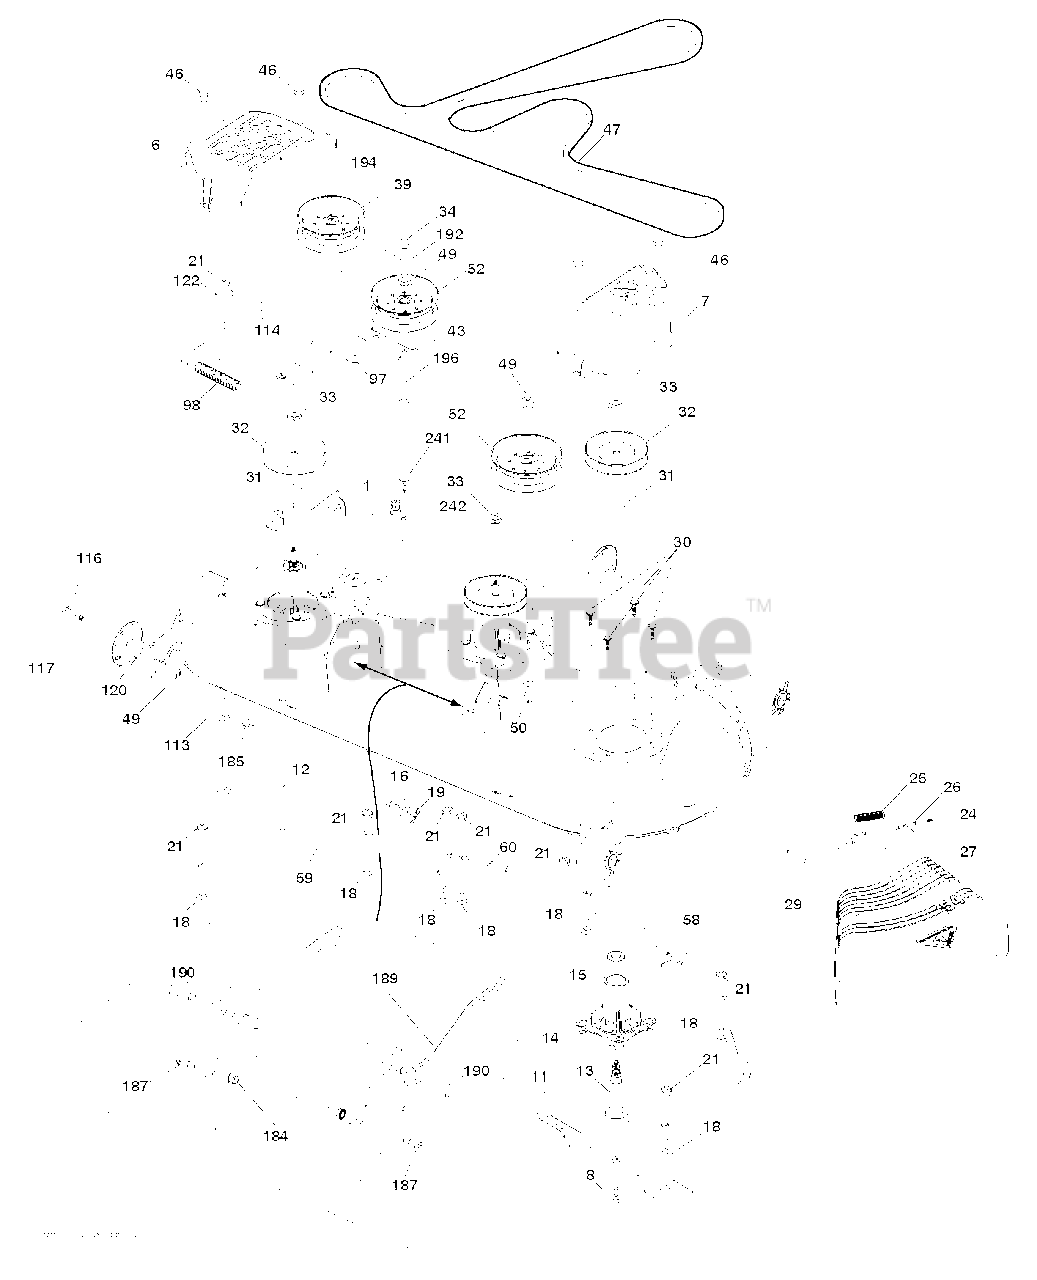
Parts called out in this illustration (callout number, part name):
1	DECK.WELDMENT.54'
6	COVER.MANDREL.LH.54"20
7	COVER.MANDREL.RH.54.20
8	BOLT.WASHER.ASM.7/16-2
11	BLADE.BAGGING.54"
12	ROD.ANTI.SWAY.48/54"TE
13	SHAFT ASM MANDREL
14	HOUSING.MANDREL.4PT.
16	WASHER
18	BOLT
19	PIN.COTTER.5/16.BOW TI
21	LOCKNUT
24	CAP-SLEEVE LT
25	SPRING, TORSION
26	NUT PUSH M
29	ROD.HINGE
30	SCREW, WASHER HEAD
31	WASHER.SPACER.MANDREL
32	PULLEY/MANDREL
33	NUT.FLANGE.LOCK.TOP
34	LOCKNUT
39	PULLEY.IDLER.4.50/HUB SPECIAL
43	ARM.IDLER
46	SCREW.1/4-20X5/8
47	BELT.DRIVE.54."2006
49	NUT LOCK FLG 3/8-16 UNC
50	BOLT
52	PULLEY.IDLER.2006
58	BAFFLE.RIGHT.54"
59	BAFFLE.LEFT.54"
60	BAFFLE CENTER 54" MOWER
98	SPRING, DECK DRIVE
113	BOLT CRT
114	ROD TENSION RELIEF
116	BOLT.SHOULDER.3/8-16X3-5/8.
117	WHEEL. GUAGE RALLY
122	BUSHING.RELIEF.TENSION
184	NUT LOCK HEX FLANGE 5/16-18
185	NUT.LOCK.FLANGE.7/16
187	STUD.FASTNER.W/ANTI-ROTATE
189	ARM.SUSPENSION.MOWER
190	BOLT.SHOULDER
192	KEEPER.BELT.IDLER.54"T
194	BOLT.HEX.WASHER.HEAD.7/16-24X
196	BOLT
241	SCREW.TT.#10-32X.5.3/8.FLANGE
242	PORT.WASHOUT
